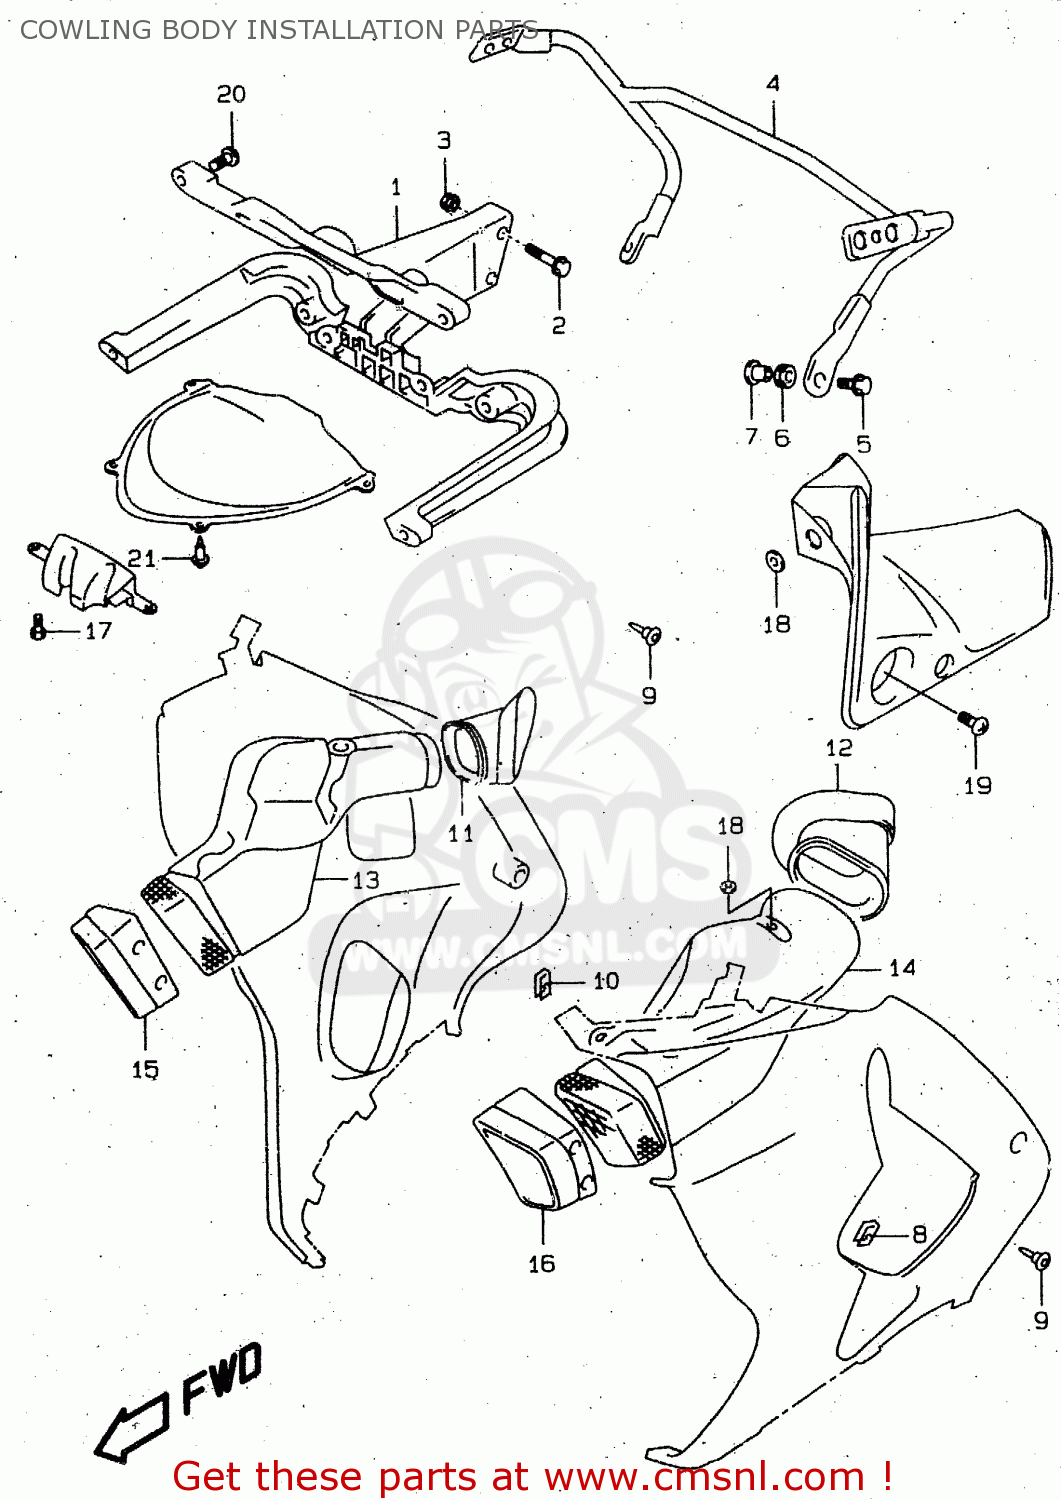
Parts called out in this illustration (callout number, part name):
1	BRACE,COWLING
2	BOLT
3	NUT
4	BRACE COMP,REAR VIEW MIRROR
5	BOLT(6X25)
6	CUSHION
7	WASHER
8	NUT,HEADLAMP HOUSING,UPPER
9	SCREW(5X16)
10	NUT
11	JOINT,AIR INTAKE,RR,R
12	JOINT,AIR INTAKE,RR,L
13	PIPE,AIR INTAKE,R
14	PIPE,AIR INTAKE,L
15	COVER,INTAKE,R
16	COVER,INTAKE,L
17	BOLT
18	CUSHION
19	SCREW
20	SCREW
21	CLIP(BLACK)
